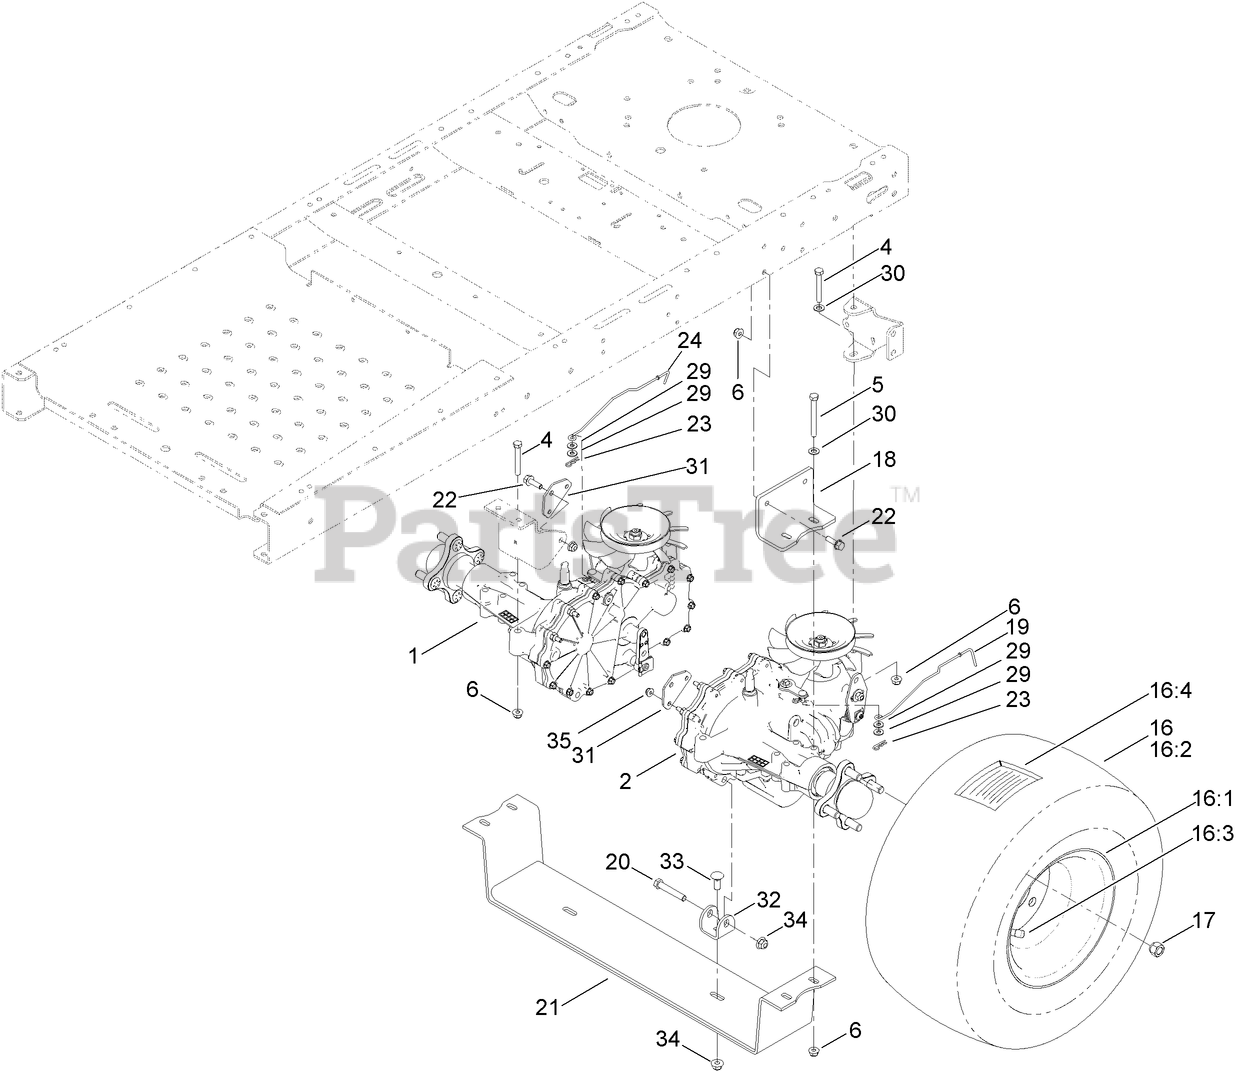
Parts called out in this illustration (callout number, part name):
1	RH HYDRO TRANSAXLE ASM
2	LH HYDRO TRANSAXLE ASM
4	SCREW-HH
5	SCREW-HH
6	NUT-HF, NI
16	4 PLY WHEEL AND TIRE ASM
16:2	TIRE-4 PLY
16:4	TUBE-INNER
17	NUT-LUG
18	MOUNT-HYDRO
19	ROD-BYPASS, LH
20	SCREW-HH
21	MOUNT-HYDRO
22	SCREW-HHF
24	ROD-BYPASS, RH
29	WASHER-FLAT
30	WASHER-PLAIN
31	PLATE-HYDRO MOUNT
32	TAB-HYDRO
33	BOLT-CARR
34	NUT-HF, NI
35	NUT-HF
